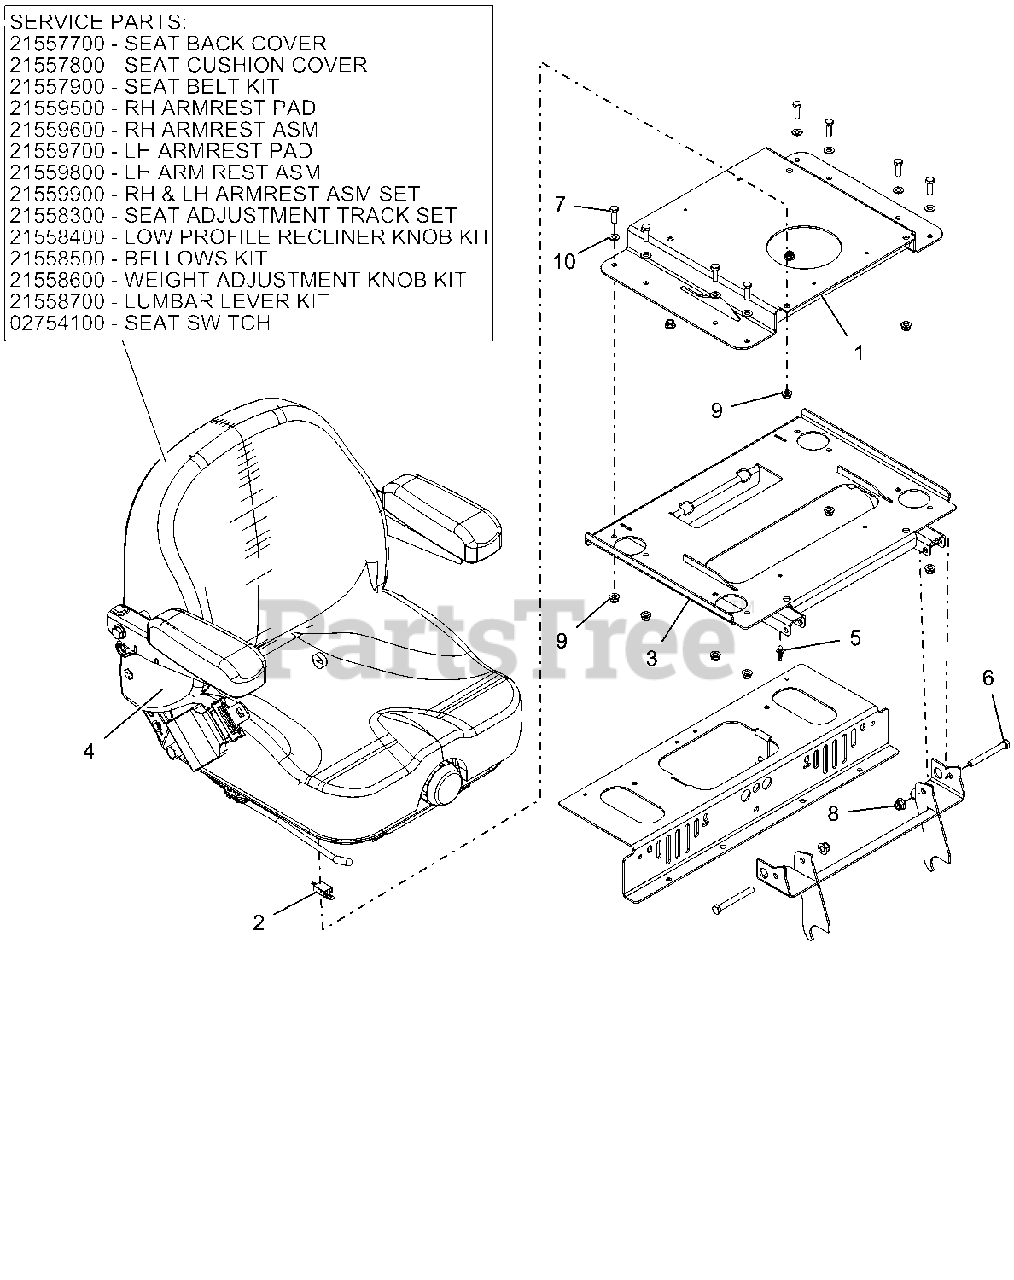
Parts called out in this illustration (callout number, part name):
1	WLDMT, SEAT BASE MOUNTING-RED
2	HARNESS, PT200 SEAT ADAPTER
3	WLDMT, SEAT ISO MOUNTING (RED)
4	SEAT, FULL SUSPENSION
4	SEAT BACK COVER
4	SEAT CUSHION COVER
4	SEAT BELT KIT
4	RH ARMREST PAD
4	RH ARMREST ASM
4	LH ARMREST PAD
4	LH ARM REST ASM
4	RH & LH ARMREST ASM SET
4	SEAT ADJUSTMENT TRACK SET
4	LOW PROFILE RECLINER KNOB KIT
4	BELLOWS KIT
4	WEIGHT ADJUSTMENT KNOB KIT
4	LUMBER LEVER KIT
4	SEAT SWITCH
5	CABLE TIE W/ TREE (.25 HOLE)
6	BLT-HEX .38-16X3.25 GR5 YWZC
7	BLT-HEX .31-18X1.00 GR5 YWZC
8	NUT-LK-NYL-FLG .38-16 YWZC
9	NUT-LK-NYL-FLG .31-18 YWZC
10	WSHR-FL-STL.344X.688X.065YWZC
